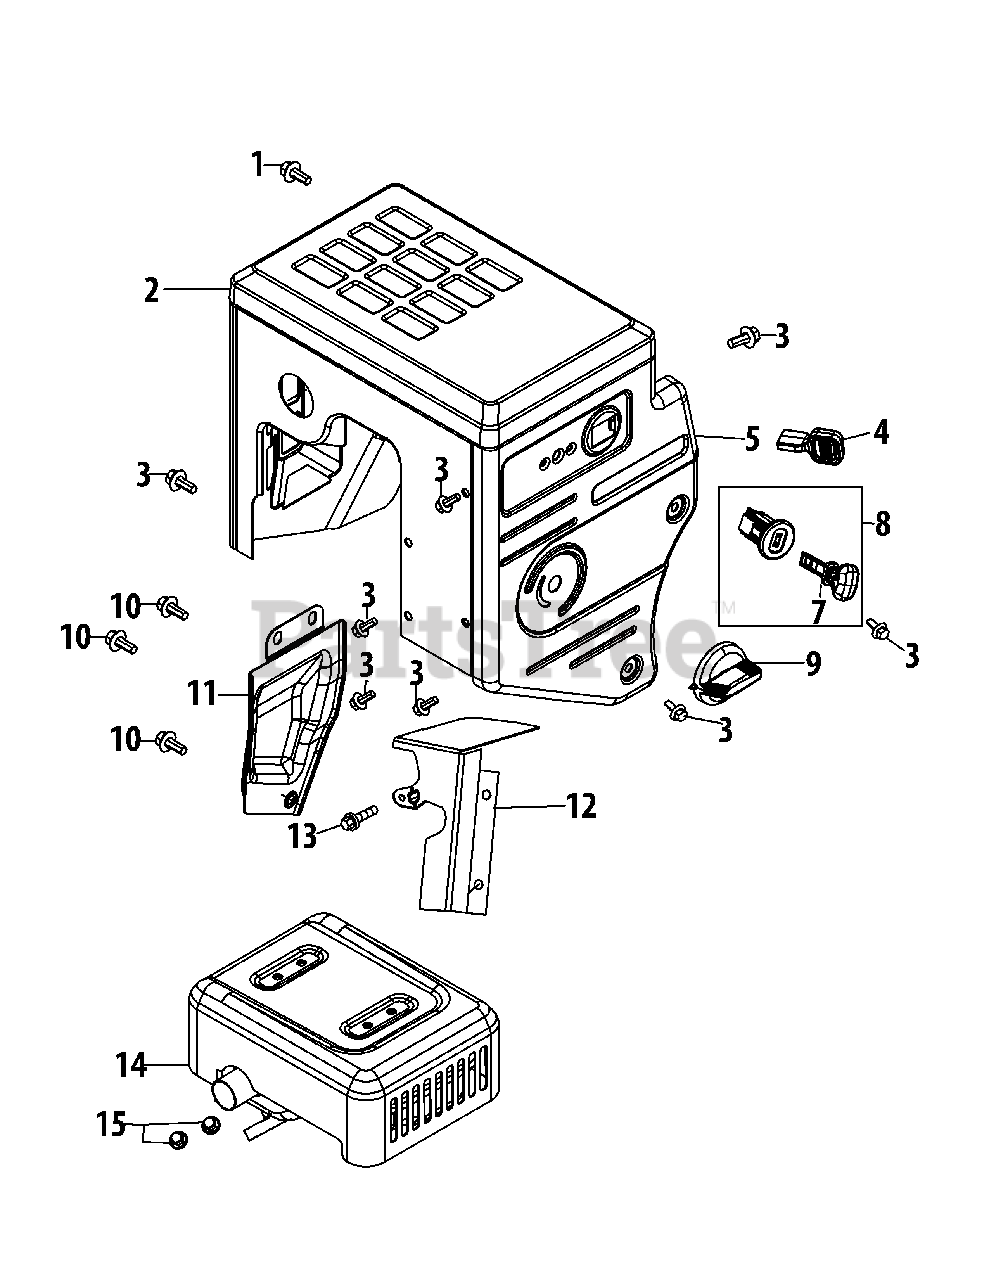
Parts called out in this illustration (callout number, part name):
1	Bolt, M6×12
2	Muffler Shield
3	Bolt M6×12
4	Throttle Control Knob
5	Control Panel
7	Key
8	Key Switch Assembly
9	Choke Knob
10	Bolt M6×10
11	Exhaust Pipe Shield
12	Carb Isolator Bracket
13	Bolt M6×16
14	Muffler Assembly
15	Nut, M8
